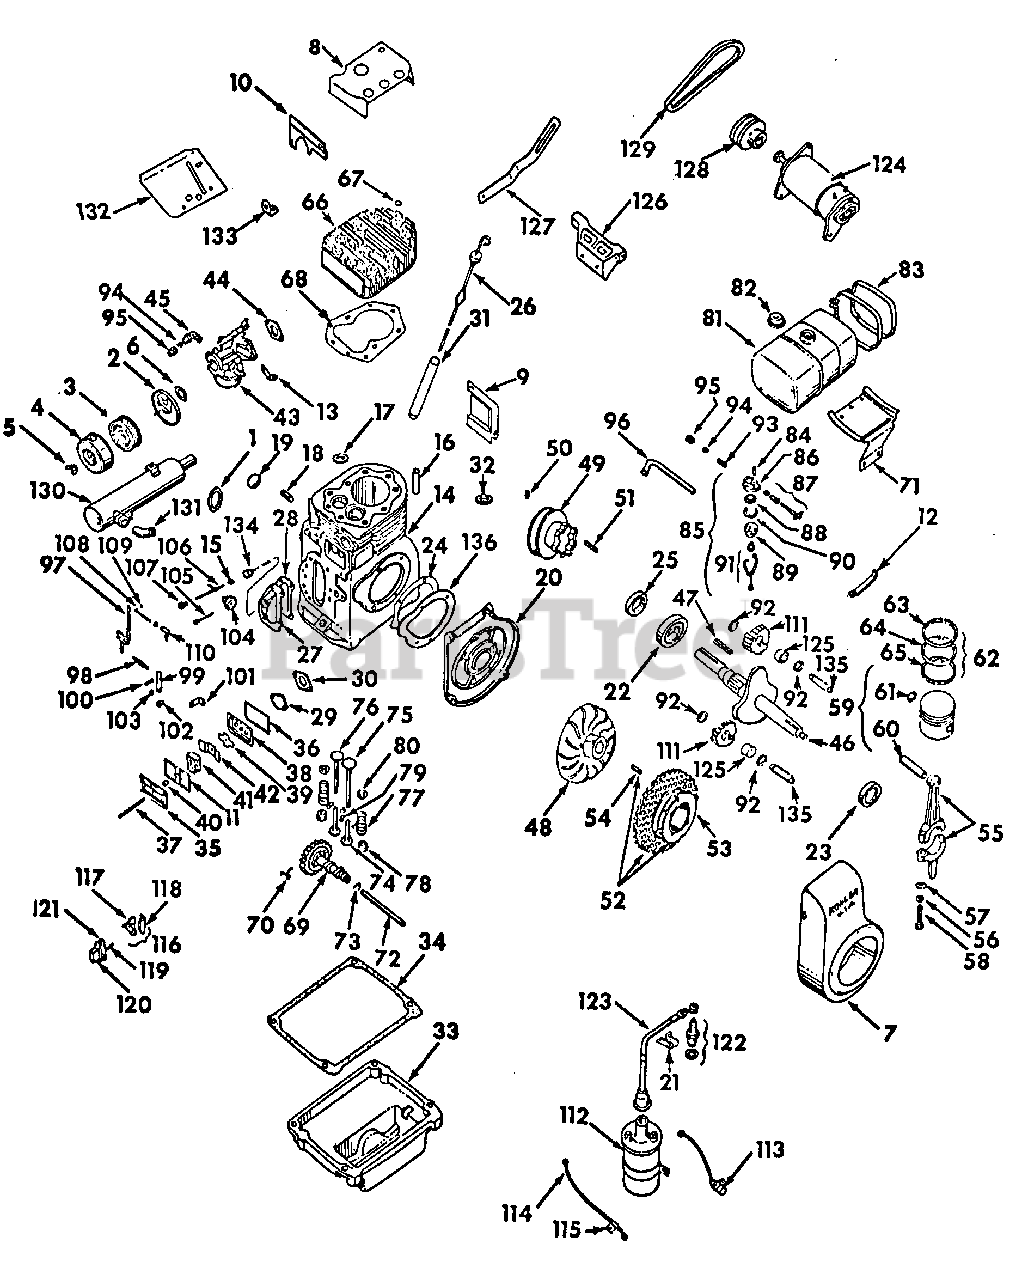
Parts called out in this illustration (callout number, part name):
1	Nut, Exhaust Muffler Elbow Lock
2	Base, Air Cleaner
3	Element, Air Cleaner Filter
4	Cover, Air Cleaner
5	Nut, Air Cleaner Wing
6	Gasket, Air Cleaner
7	Housing Assy, Blower
8	Baffle, Cylinder Head Air
9	Baffle, Cylinder Air
10	Baffle, Housing Side Air
11	Gasket, Valve Cover
12	Bracket, Throttle Cable
13	Bracket, Choke
14	Crankcase Assy
15	Bearing, Needle
16	Guide, Valve
17	Insert, Exhaust Valve
18	Shaft, Governor
19	Plug, 1-1/8 Expansion (Crankcase)
20	Plate, Crankcase Brg
21	Clip, Spark Plug Cable
22	Bearing, Crankcase Ball
23	Seal, Crankcase Brg Plate Oil
24	Gasket, Brg Plate, .005
25	Seal, Crankcase Oil
27	Cover, Camshaft
28	Gasket, Camshaft Cover
29	Cover, Fuel Pump Pad
30	Gasket, Fuel Pump Pad Cover
31	Tube, Oil Fill
32	Insert, Intake Valve
33	Base, Oil Pan
34	Gasket, Oil Pan Base
35	Cover, Breather
36	Gasket, Breather
37	Stud, Breather Cover
38	Plate Assy, Breather
39	Shim, Breather
40	Seal, Breather
41	Filter, Breather
42	Baffle, Breather
43	Carburetor Assy
44	Gasket, Carburetor
45	Elbow, Carburetor to Fuel Line
47	Key, Crankshaft
49	Pulley w/Clutch Drive Plate, Flywheel
50	Screw, Flywheel Pulley Set
51	Key, 1/4 X 7/8 Sq Parallel
52	Cup Assy, Flywheel Drive
53	Screen, Drive Cup Grass
54	Pin, Flywheel Drive Cup
55	Rod Assy, Connecting, Std
56	Washer, 3/8 Hv Connecting Rod Lock
57	Washer, Connecting Rod
58	Screw, Connecting Rod
59	Piston Assy, Std
60	Pin, Piston, Std
61	Retainer, Piston Pin
62	Ring Set, Piston, Std
63	Ring, Top Compression
64	Ring, Center Compression
65	Ring, Oil Control
66	Head, Cylinder
67	Washer, Cylinder Head
68	Gasket, Cylinder Head
69	Camshaft Assy
70	Spring, Camshaft Actuating
71	Bracket, Fuel Tank
72	Pin, Camshaft
73	Shim, Camshaft, .005
74	Tappet Assy, Valve
75	Valve, Intake
76	Valve, Exhaust
77	Spring, Valve
78	Rotator, Valve
79	Key, Valve Spring Retainer
80	Retainer, Valve Spring Upper
81	Tank Assy, Fuel w/Filler Cap
82	Cap, Fuel Filler
83	Strap, Fuel Tank
84	Nipple, 1/8 X 3/4 C-Z Pipe
85	Filter Assy, Fuel
86	Body, Fuel Filter
87	Valve Assy, Needle
88	Screen, Filter
89	Bowl, Fuel Filter Glass
90	Gasket, Fuel Filter Bowl
91	Bail Assy, Fuel Filter Bowl
92	Kit, Spacer Dyn Bal
93	Connector, Fuel Filter
94	Sleeve, Fuel Line
95	Nut, Fuel Line
96	Line, Fuel Filter to Carburetor Fuel
97	Lever, Governor
98	Spring, Governor
99	Bracket, Speed Control
100	Clamp, Control Bracket
101	Bracket, Adjusting Screw
102	Spacer, Adjusting Screw
103	Washer, Adjusting Screw Spacer
104	Gear Assy, Governor
105	Pin, Governor Stop
106	Shaft Assy, Governor Cross
107	Bushing, Cross Shaft
108	Rod, Ball Joint Throttle
109	Retainer, Throttle Rod
110	Joint, 10-32 X 1/4 Ball
111	Gear Balance
112	Coil, Ignition
113	Condenser, Ignition Coil
114	Cable Assy, Condenser to Breaker
115	Clip, Condenser to Breaker Cable
116	Bracket & Breaker Assy
117	Breaker Point Set
118	Bracket, Point Breaker
119	Rod, Breaker
120	Cover, Breaker
121	Gasket, Breather Cover
122	Plug, Spark (Champion)
123	Kit, Hi-Tension Spark Plug Cable Lead
124	Motor Generator
125	Bearing Assy, Needle
126	Bracket, Motor Generator Mounting
127	Brace, Motor Generator Adjusting
128	Pulley, Motor Generator Drive
129	Belt, Motor Generator Drive
130	Muffler Exhaust
131	Tube, Exhaust Muffler
132	Baffle, Heat
133	Angle, Hanging Strap
135	Shaft, Balance Gear Stub
136	Gasket, Bearing Plate
